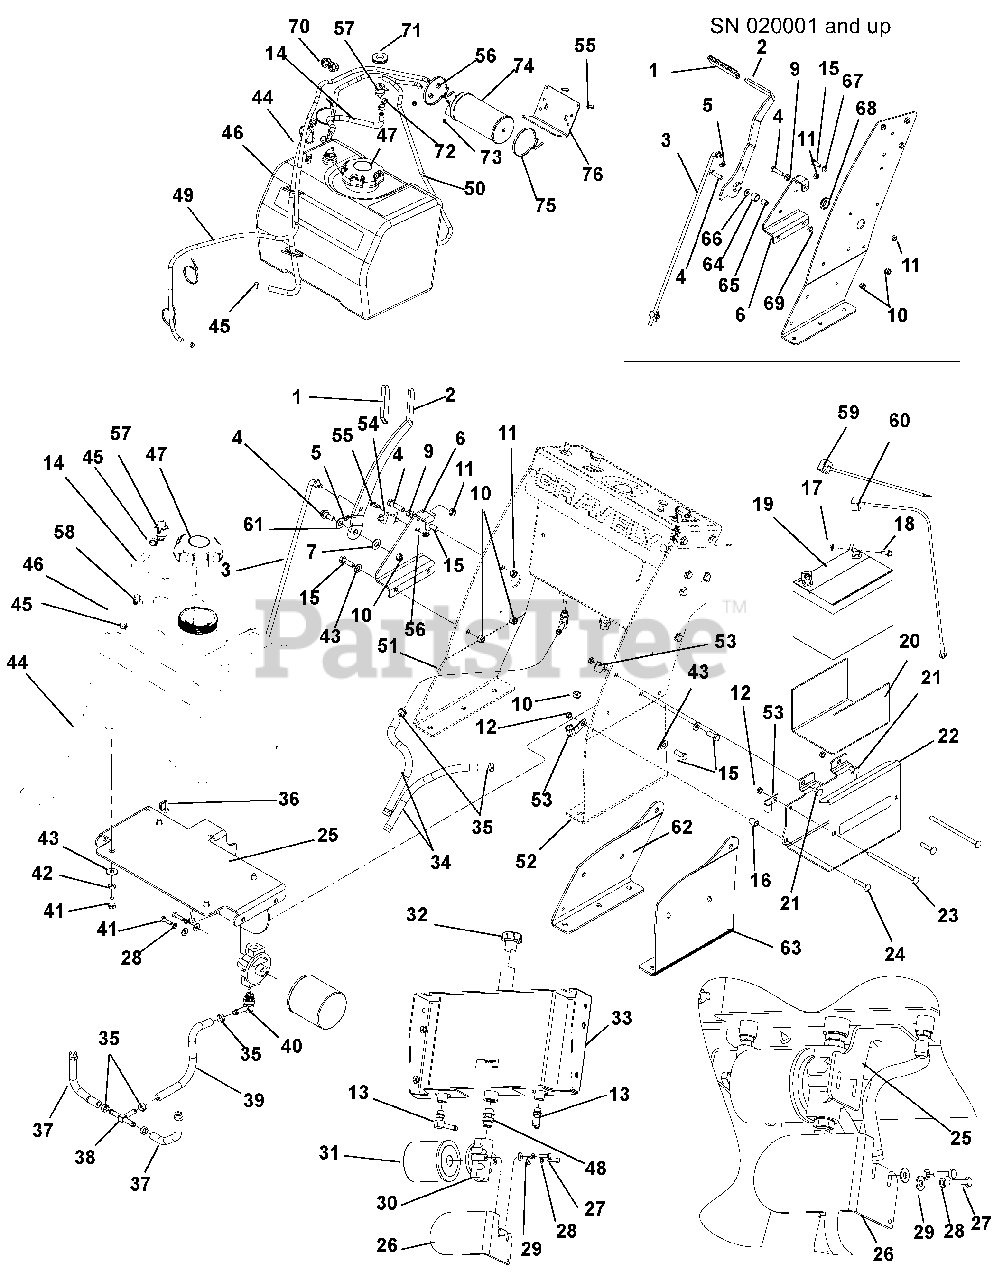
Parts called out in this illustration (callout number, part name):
1	GRIP
2	LEVER, HAND BRAKE (SN 000101 - 020000)
3	ROD, DRIVE CONTROL FW
4	BLT-HEX .38-16X1.50 GR5 YWZC
5	RING, RUE .375 X .054 X 1.254
6	LOCATOR, BRAKE ARM WD (SN 000101 - 010000)
7	BUSHING, BRAKE LEVER STAND OFF (SN 000101 - 020000)
8	BOLT, .38-16 X 1.00 HEX 5 Y
9	LOCKNUT, 3/8-16 WHIZ Y
10	LOCKNUT, 3/8-16 NYLOC Y
11	LOCKNUT, 3/8-16 CENTER Y
12	LOCKNUT, 5/16-18 NYLOC Y
13	FITTING, 90 9/16 MOR X 3/8 HOSE (SN 000101 - 020000)
14	HOSE, FUEL HYDRO TANK - ROV
15	BOLT, .38-16 X 1.00 HEX 5 Y
16	BUSHING, .364X.540X.700 Y
17	LOCKNUT, 1/4-20 WHIZ Y (SN 000101 - 020000)
18	BOLT, .25-20 X .75 WSH Y (SN 000101 - 020000)
19	BATTERY, 12V-U1-CCA270MIN
20	STRIP, BATTERY INSULATOR
21	BOLT, RDHDSQNK .31-18 X .75 G5Y
22	TRAY, BATTERY ELEC (SN 000101 and 010000)
23	BOLT, 5/16-18 X 6.00 CRG 2 Y
24	BOLT, RDHDSQNK .31-18 X 1.50 G5YZ
25	BRACKET, FUEL TANK RMHF (SN 000101 - 010000)
26	GUARD, HYDRO FILTER FLWLK (SN 000101 - 010000)
27	BOLT, .25-20 X 1.00 HEX 5 Y (SN 000101 - 029999)
28	WASHER, LOCKING .25 x .062 REGULAR
29	WASHER, FLAT-STL.312 x .734 x .065
30	HEAD, OIL FILTER
31	FILTER, OIL
32	CAP, OIL FILL BREATHER
33	WLDT, TANK (SN 000101 - 020000)
34	HOSE, HYD .375 X 11.5 (SN 000101 - 020000)
35	CLAMP, HOSE - 1/2" PINCH
36	CABLE TIE, .15 X 8.50
37	HOSE, HYD 3/8 X 6.00
38	FTG, TUN 3/8 HOSE
39	HOSE, HYD. .375 X 12
40	FTG, 90 BRB-OR 4601-06-08
41	BOLT, .38-16 X .750 HEX 5 Y
42	WASHER, .375 MED SPRG LOCK Y
43	WASHER, FLAT-STEEL .406 X .812 X .065
44	HOSE, FUEL 1/4 X 18.00
45	CLAMP, HOSE - 1/2" SPRING
46	ASSY, FUEL TANK (SN 000101 - 021000)
47	CAP, FUEL
48	STRAIGHT UNION SAE 8
49	HOSE, ACTIVE FUEL
50	HOSE, FUEL HYDRO ROV - CC
51	WLDT, RH UPRIGHT TOWER WDTL WALK (988157, 158, 159) (SN 000101 - 010000)
52	WLDT, LH UPRIGHT TOWER WDTL WALK (988157, 158, 159) (SN 000101 - 010000)
53	P-CLIP, .500 INSULATED (988157, 158)
54	SWITCH- DOUBLE POLE N.O./N.O.
55	SCREW, 10-24 X .75 HWH
56	NUT, LOCK 10-24 NYLOC (SN 000101 - 020000)
57	VALVE, COMBINATION
58	VALVE, REMOTE ROLL OVER
59	CABLE, BATTERY GROUND 25"
60	CABLE, BATTERY - 25" POSITIVE
61	WASHER-FL-STL .438 X 1.00 X .083
62	61" WALK TOWER DBL PLATE RH (988159, 169)
63	61" WALK TOWER DBL PLATE LH (988159, 169)
64	PARK BRAKE HANDLE BUSHING (SN 020000 and up)
65	PARK BRAKE LEVER SPACER (SN 020000 and up)
66	WSHR-FL-STL.38X.875X.083 YWZC
67	WSHR-FL-STL.406X.812X.065 YWZ
68	GROMMET:RUB:.88IDx1.38ODX.14GR
69	NUT-SPNLK-FLG .375-16 YWZC
70	BUSH, PANEL SNAP .687X.875X.56
71	GROMMET, REMOTE ROV
72	CLAMP, DBL PINCH 5/16" - 7/16" (SN 021000 and up)
73	CLAMP - HOSE, SPRING .188
74	400 CC CARBON CANISTER 3/16 PT
75	CABLE TIE, .19 X 14.4
76	BRKT, CARB CANISTER MTG (SN 021000 and up)
